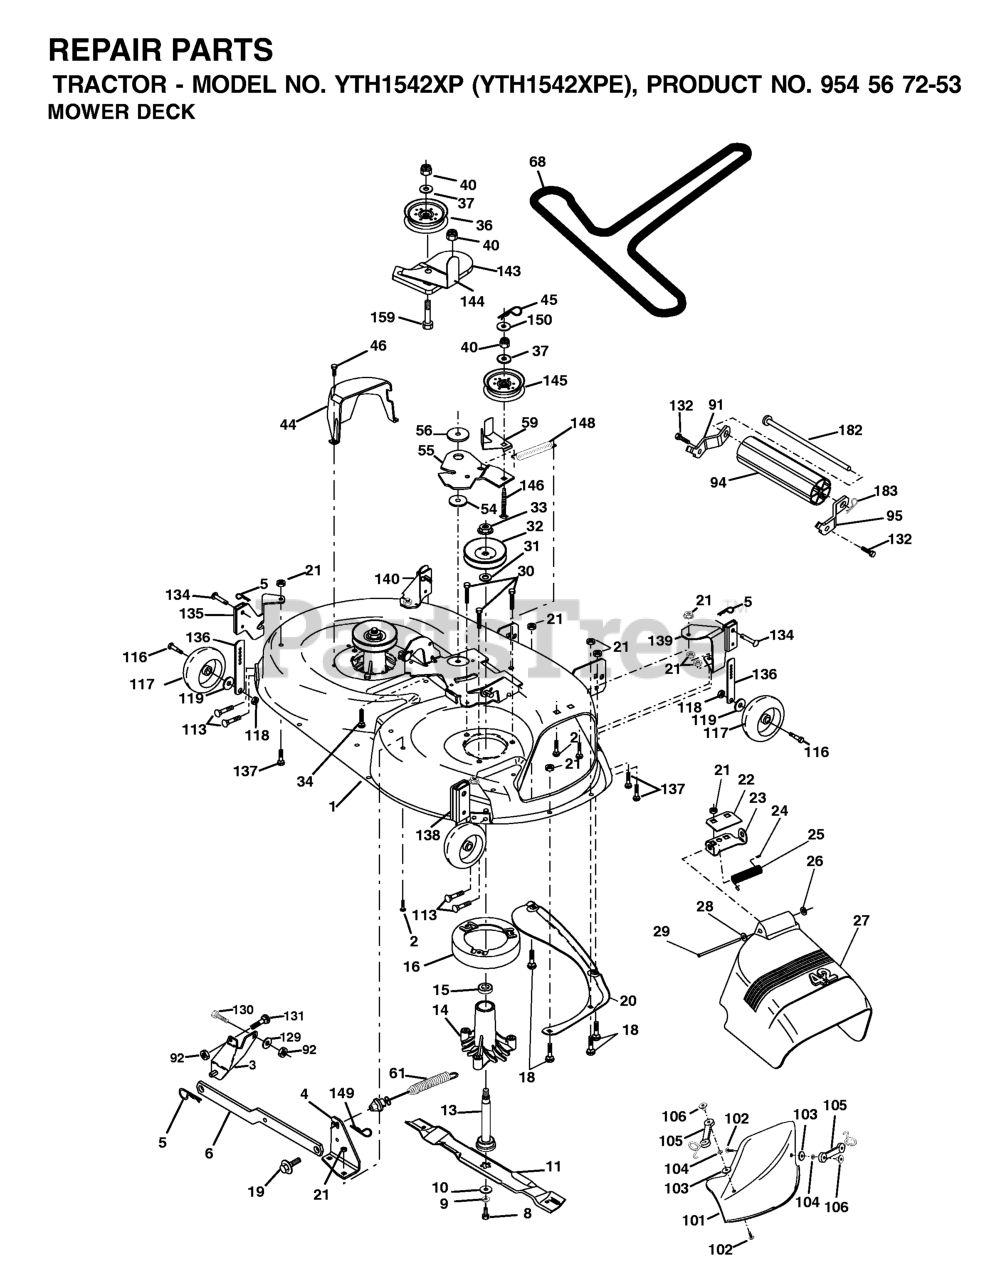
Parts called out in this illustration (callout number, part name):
1	DECK, 42"
2	RP BOLT 5/16-18 X3/4 ZN/YEL GR
3	BRKT ASM SWAY BAR
4	BRACKET SWAY BAR 42" DECK
5	RETAINER-SPRNG RB
6	BAR SWAY DECK
8	BLADE BOLT
9	LOCKWASHER
10	WASHER.BLADE
11	Blade Mower 42" High Perf.
13	SHAFT ASM VENT
14	HOUSING.MANDREL.VENTED (MACHD)
16	STRIPPER.MANDREL.ROUND.BLACK
18	BOLT
19	BOLT SHD 5/16-18
20	BAFFLE.VORTEX
21	LOCKNUT
22	STIFFENER BRACKET
23	DEFLECTOR BRACKET
24	CAP-SLEEVE LT
25	SPRING TORSION
26	NUT PUSH M
27	SHIELD DEFLECTOR
28	Washer 11/32 x 5/8 x 16 Ga SD
29	ROD.HINGE
30	SCREW, WASHER HEAD
31	WASHER
32	PULLEY MANDREL
33	NUT, FLG TOPLOCK 9/16"
36	PULLEY.IDLER.FLAT
37	WASHER
44	GUARD MANDREL LH BLACK
45	RETAINER M
46	SCREW.1/4-20X5/8
54	HARDENED WASHER
55	ARM IDLER 42" MOWER LT/YT
56	SPACER RETAINER
59	GUARD TUV IDLER
61	SPRING EXT ELEC CLUTCH
68	V-BELT PRIMARY 42"
91	BRACKET ASM NOSEROLLER LH
92	NUT.71038.31-18.HEX.NYLOCK
94	NOSE ROLLER
95	BRACKET ASM NOSEROLLER RH
101	COVER MULCH 42"
102	SCREW
104	LOCKWASHER #10
105	LATCH ASSY
106	WELDNUT
113	SCREW 5/16"
116	BOLT M
117	WHEEL.GAUGE.STANDARD
118	LOCKNUT
119	WASHER.5/16.FLAT.STE.STD.
129	WASHER
131	BOLT D
132	SCREW 3/8-16X3/4
134	RIVET.PIN.HEAD.YELLOW.
135	BRACKET ASM, WHEEL
136	BAR.ADJUST.WHEEL.ANTI.SCALP.BL
137	BOLT.CARR.5/16-18X5/8.SHORT
138	BRACKET.ASM.WHL.GA.R.RH.42".GR
139	BRACKET ASM, WHEEL
140	BRACKET ASM, WHEEL
143	BRACKET, ARM IDLER
144	KEEPER BELT 42" CLUTCH
145	PULLEY.IDLER.FLAT.PLATED
146	BOLT, CARRIAGE IDLER BLACK
148	IDLER RETURN SPRING
149	SPRING.RETAINER.YELLOW.ZINC
182	ROD ROLLER NOSE STANDARD
183	SPRING RETAINER
